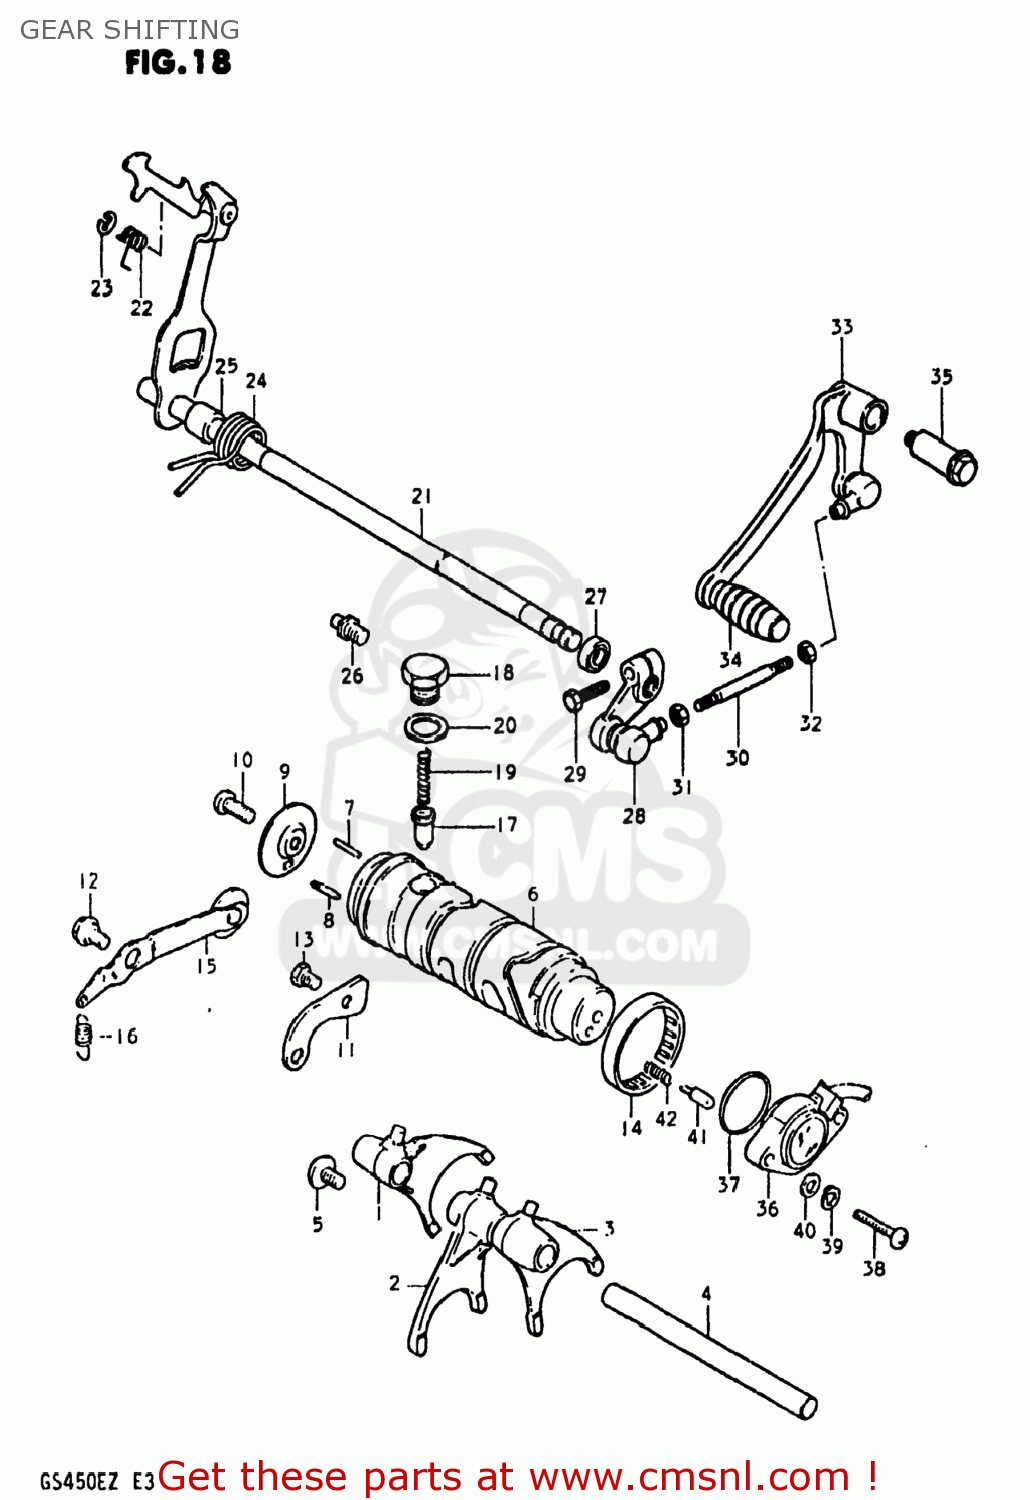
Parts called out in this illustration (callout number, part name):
1	FORK,GEAR SHIFT NO.1
2	FORK,GEAR SHIFT NO.2
3	FORK,GEAR SHIFT NO.2
4	SHAFT,GEAR SHIFT FORK
5	SCREW
6	CAM,GEAR SHIFT
7	PIN(4X18.5)
8	PIN
9	RETAINER,GEAR SHIFT CAM DR PIN
10	SCREW
11	GUIDE,GEAR SHIFTING CABLE
12	BOLT
13	BOLT, UPPER
14	BEARING(40X47X12)
15	STOPPER,GEAR SHIFT CAM NO.1
16	SPRING
17	STOPPER,GEAR SHIFT CAM NO.2
18	HOLDER,GEAR SHIFT CAM STOP SPR
19	SPRING
20	GASKET(14X19.2X2) (NAS)
21	SHAFT,GEAR SHIFT
22	SPRING
23	E RING
24	SPRING
25	SPACER(12X20X15.3)
26	STOPPER,GEAR SHIFT CAM
27	OIL SEAL
28	ARM,GEAR SHIFT LINK
29	BOLT
30	ROD,GEAR SHIFT LINK
31	NUT
32	NUT
33	LEVER ASSY,GEAR SHIFT
34	RUBBER,GEAR SHIFT PEDAL
35	SHAFT,GEAR SHIFT LEVER
36	TERMINAL BASE ASSY,GEAR SHIFT
37	O-RING (D:2.4 ID:26.2)
38	SCREW 5X20
39	LOCK WASHER
40	WASHER
41	PIN(5X15.5)
42	SPRING
